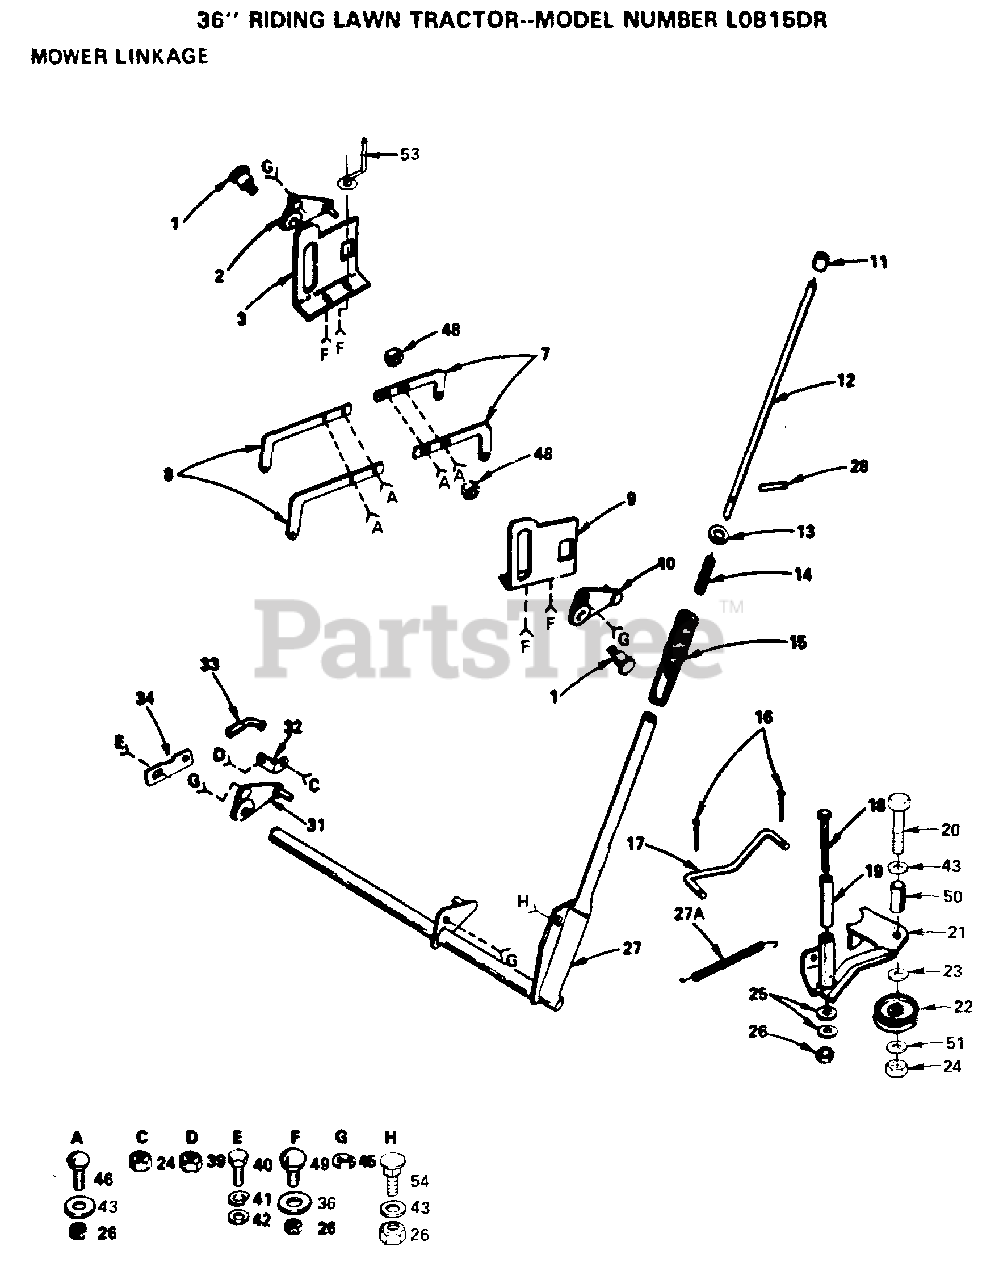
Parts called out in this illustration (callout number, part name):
1	SHOULDER BOLT T
3	SLIDE BRKT T
7	LIFT LINK ADJ T
8	LIFT LINK LT
9	SLIDE BRKT T
12	ROD PLUNGER T
13	WASHER
15	GRIP LT
19	INNER SLEEVE T
20	BOLT LT
22	PULLEY LT
23	WASHER
27	LIFT SHAFT ASST T
31	LIFT ARM ASSY T
32	ADJ BRACKET L T
39	GRIPCO NUT
40	BOLT LT
41	LOCKWASHER
42	WASHER
43	WASHER M
45	E-RING LT
46	BOLT
48	NUT LTV
49	BOLT
50	SPACER LT
51	WASHER
53	SNUBBER-BELT
